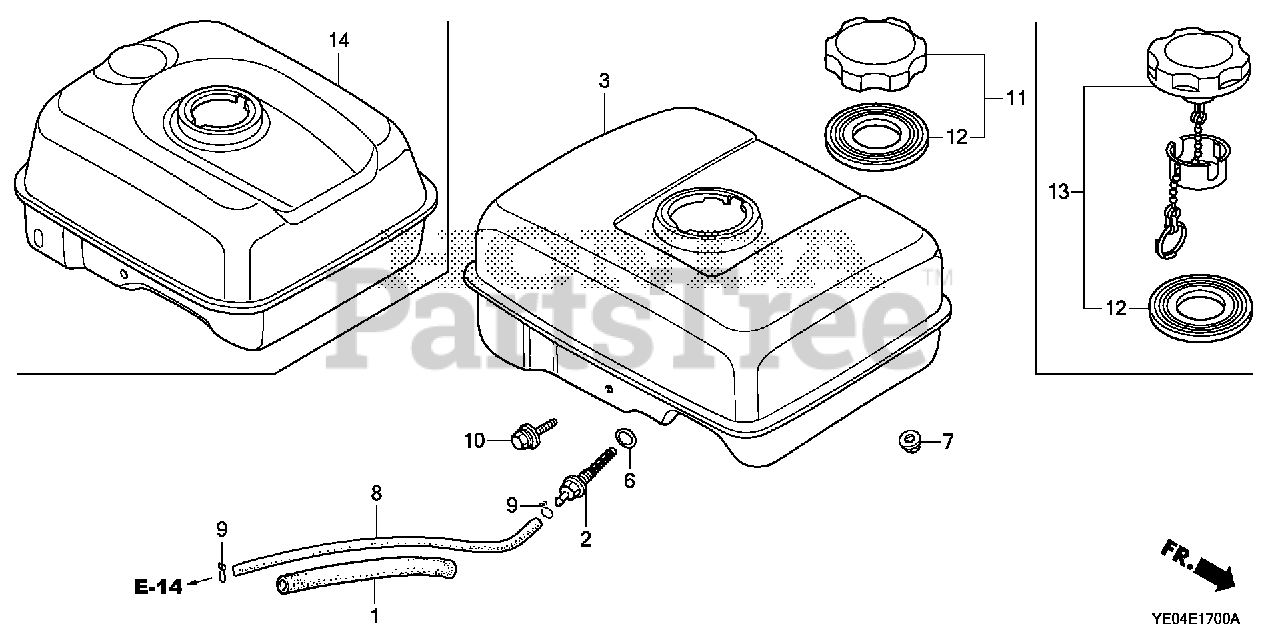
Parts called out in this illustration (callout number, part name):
1	RUBBER, SUPPORTER (107MM)
2	JOINT, FUEL TANK
3	TANK, FUEL *NH31* (MCKINLEY WHITE)
6	O-RING (13.5X1.5) (ARAI)
6	O-RING (14MM) (NOK)
7	NUT, FLANGE (6MM)
8	TUBE, FUEL (4.5X140) (FKM)
9	CLAMP, TUBE (D8)
10	BOLT, FLANGE (6X29)
11	CAP, FUEL FILLER (CHROME PLATED)(RADICON)
12	GASKET, FUEL FILLER CAP (39X62X3) (RADICON)
